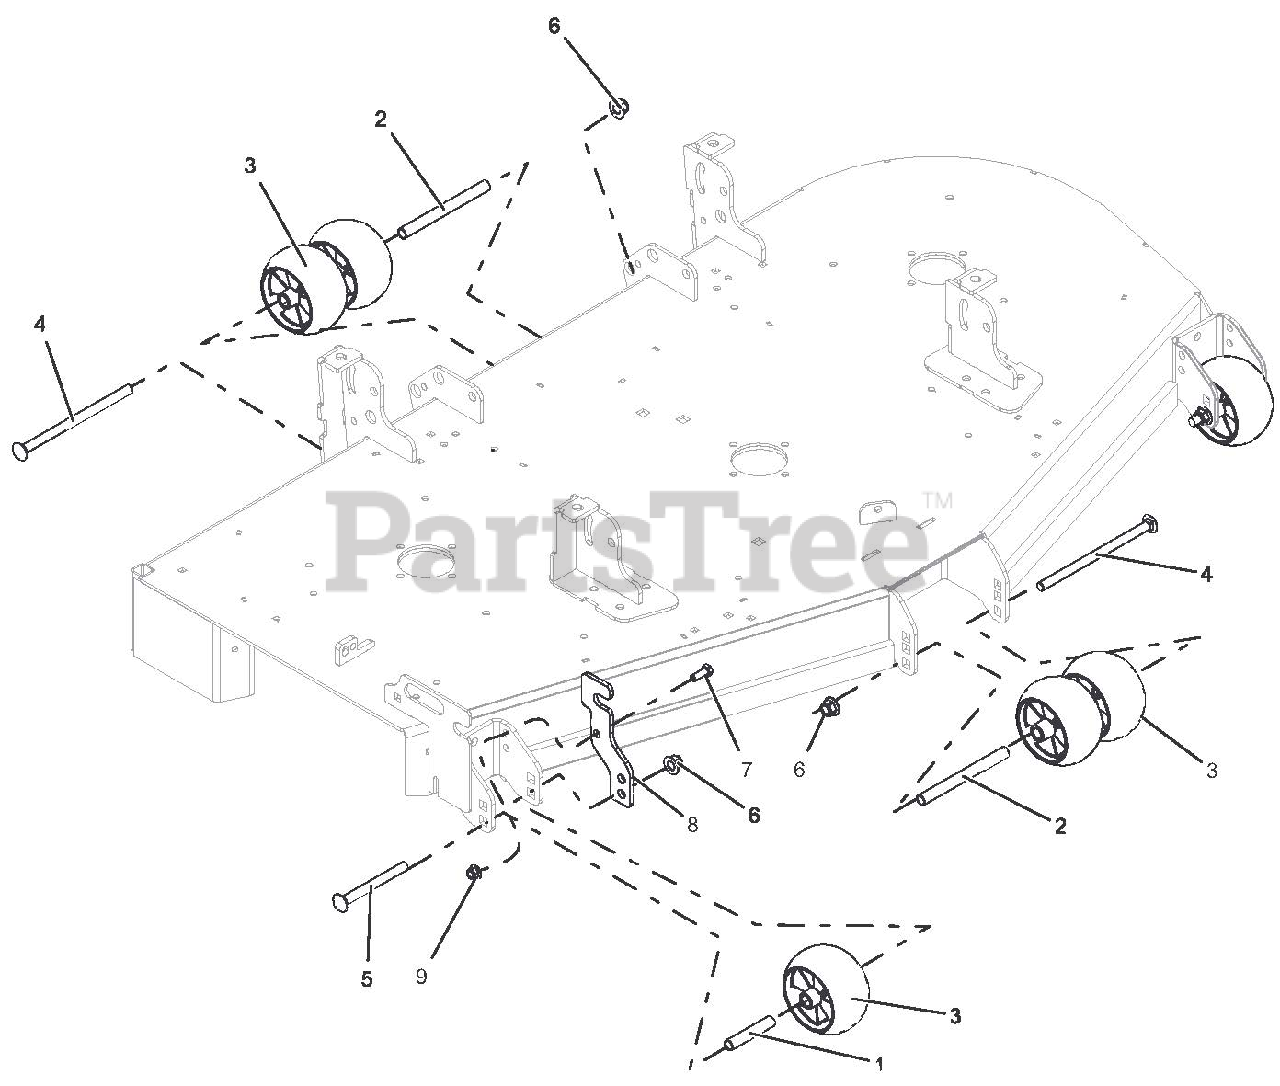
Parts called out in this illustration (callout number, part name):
1	SPACER, .510X.625X3.35
2	SPACER, .510 X .625 X 6.50
3	ANTI-SCALP WHEEL - 5X3 CTR
4	BLT-RDHDSQNK .50-13X8.50 Y
5	BLT-RDHDSQNK .50-13X5.00 G5 YWZC
6	NUT-LK-NYL-FLG .50-13 YWZC
7	BLT-HEX .38-16X1.00 GR5 YWZC
8	CHUTE STORAGE BRACKET-RED
9	NUT-LK-NYL-FLG .38-16 YWZC
